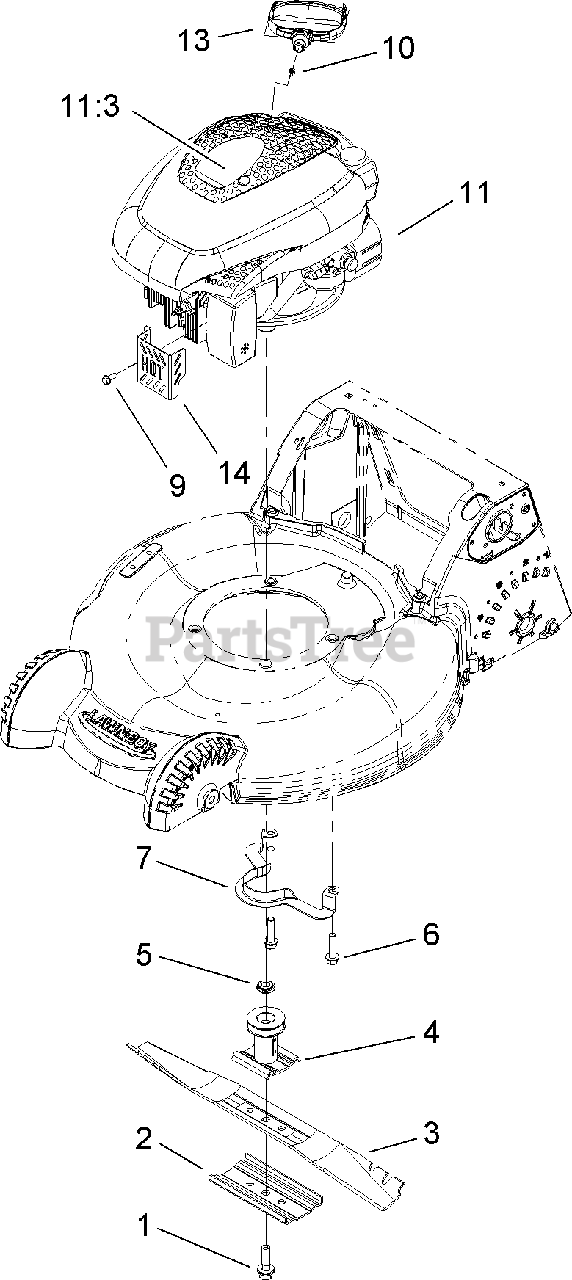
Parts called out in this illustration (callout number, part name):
1	BOLT-BLADE
2	SUPPORT-BLADE
3	BLADE-21 INCH
4	BLADE DRIVER ASM
5	Spacer-Driver
6	SCREW-HWH
9	SCREW-HWH
10	STOP-ROPE
11:3	DECAL-ENGINE
13	HANDLE-RECOIL
14	GUARD-MUFFLER
